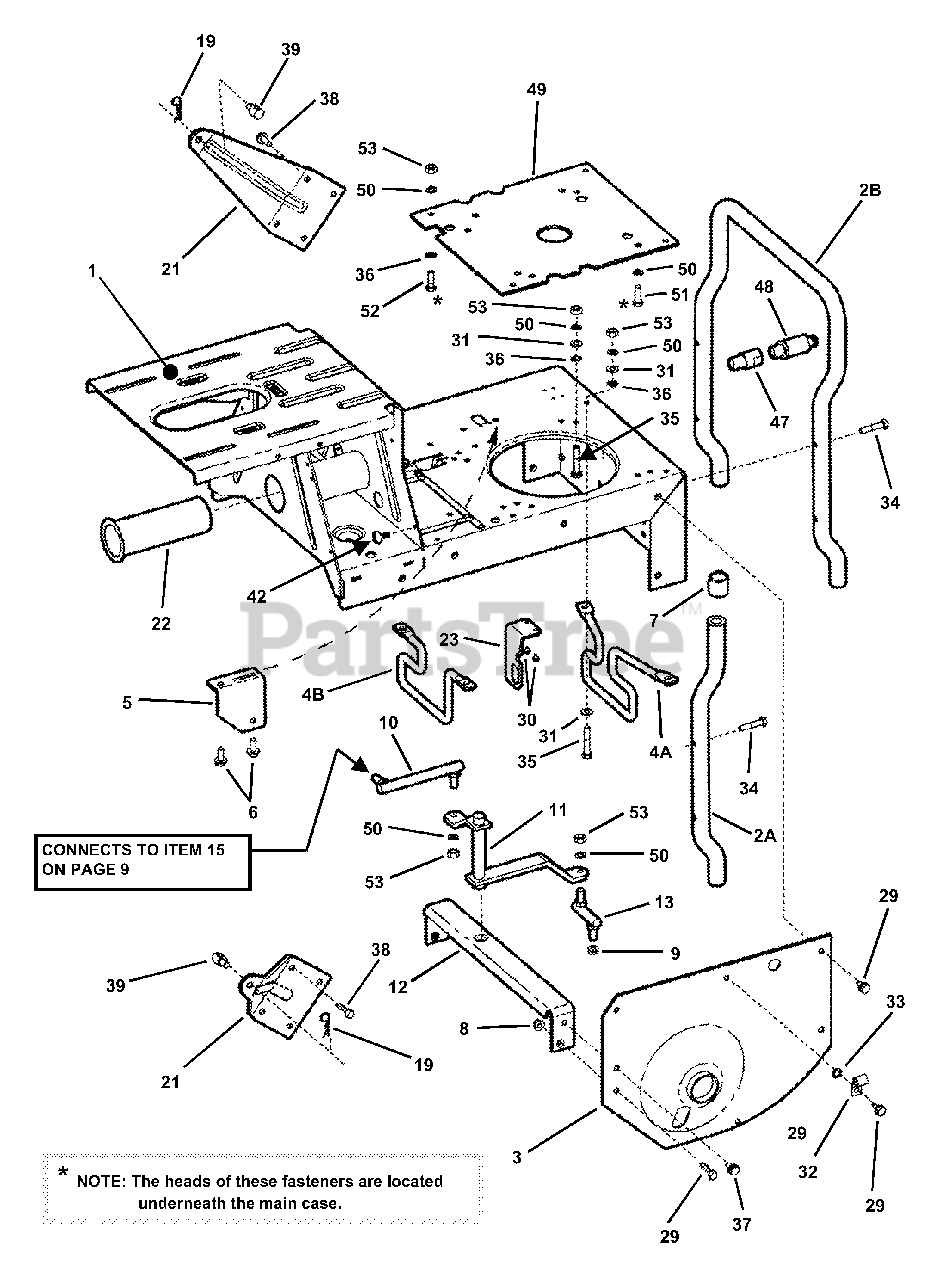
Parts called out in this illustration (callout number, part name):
1	WELDMENT, Main Case
2A	BUMPER, Rear
2B	BUMPER (1-piece) (33" Deck)
3	FENDER, Left Hand
4A	GUIDE, Belt
4B	GUIDE, Belt
5	BRACKET, Drive Support
6	BOLT, 5/16-18 X 3/4" Hex Flange Lock, Grade 5
7	CAP, Bumper
8	NUT, 5/16-18 Hex Fl. Lock
9	NUT, 5/16-24 Hex Flange Lock
10	LINK, Shift (Long)
11	ARM, Shift
12	BRACE, Cross
13	LINK, Shift (Short)
19	HAIRPIN, 3/32 X 1-1/2"
21	WING, Rear
22	BUSHING, Pilot
23	BRACKET, Switch
29	SCREW, 5/16-18 x 5/8" Self Tap
30	SCREW, #10-32 x 1/4" Hex Washer Self-Tap
31	WASHER, 5/16" Flat
32	CLIP, Wire
33	WASHER, 5/16" Internal Tooth Lock
34	SCREW, 5/16-18 x 1-1/2"
35	SCREW, 5/16-24 x 1-1/2" Hex Head Cap, Grade 5
36	RETAINER, 5/16 Bolt
37	SCREW, 5/16-18 x 3/4" Cap
38	SCREW, 5/16-18 X 3/4" Hex Self-Tap
39	SWIVEL
42	FASTENER, 1/4" Ratchet
47	OIL DRAIN, Short
48	ASSEMBLY, Oil Valve
49	PLATE, Engine (Kohler engine)
50	WASHER, 5/16" Split Lock
51	BOLT, M8-1.25 x 25mm, Self-Tap (Kohler)
52	SCREW, 5/16-24 x 1" Gr. 5
53	NUT, 5/16-24 Hex, Grade 5
